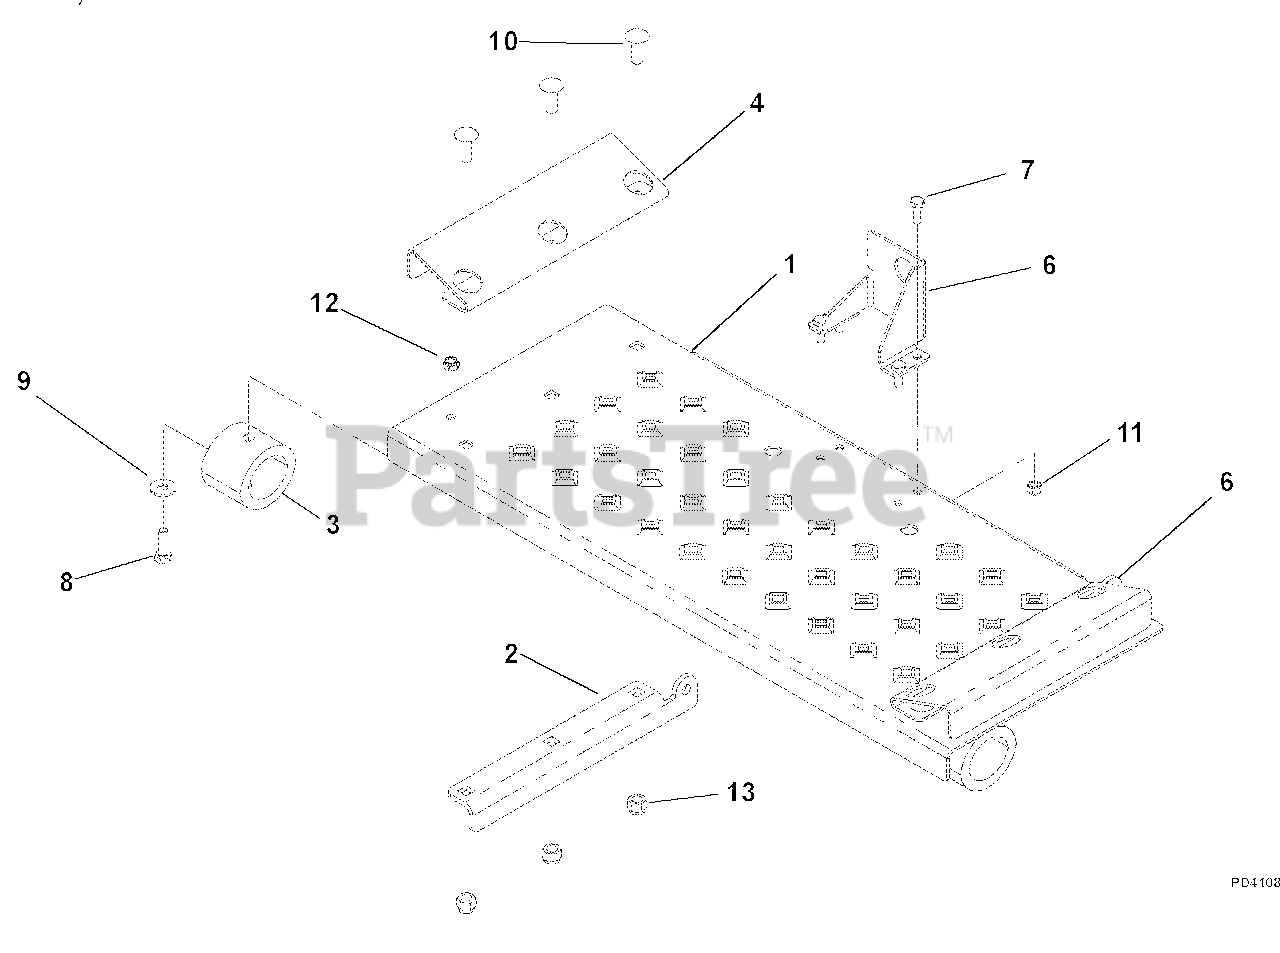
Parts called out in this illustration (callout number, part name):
1	Plate, Platform
2	Plate, Platform Tab RH
3	Bumper, Miner GBR-6
4	Wedge, Platform
5	Plate, Platform Tab LH
6	Anchor, OPC
7	Bolt, Hex .25-20 x .75 Grade 5
8	Bolt, Hex .31-18 x 1.00 Grade 5
9	Washer, Flat, Steel .38 x .875 x .083
10	Bolt, Round Head Square Neck .38 x 1.00
11	Nut, Locking, Nylon .250-20
12	Nut, Locking, Nylon .312-18
13	Nut, Locking, Nylon .38-16
